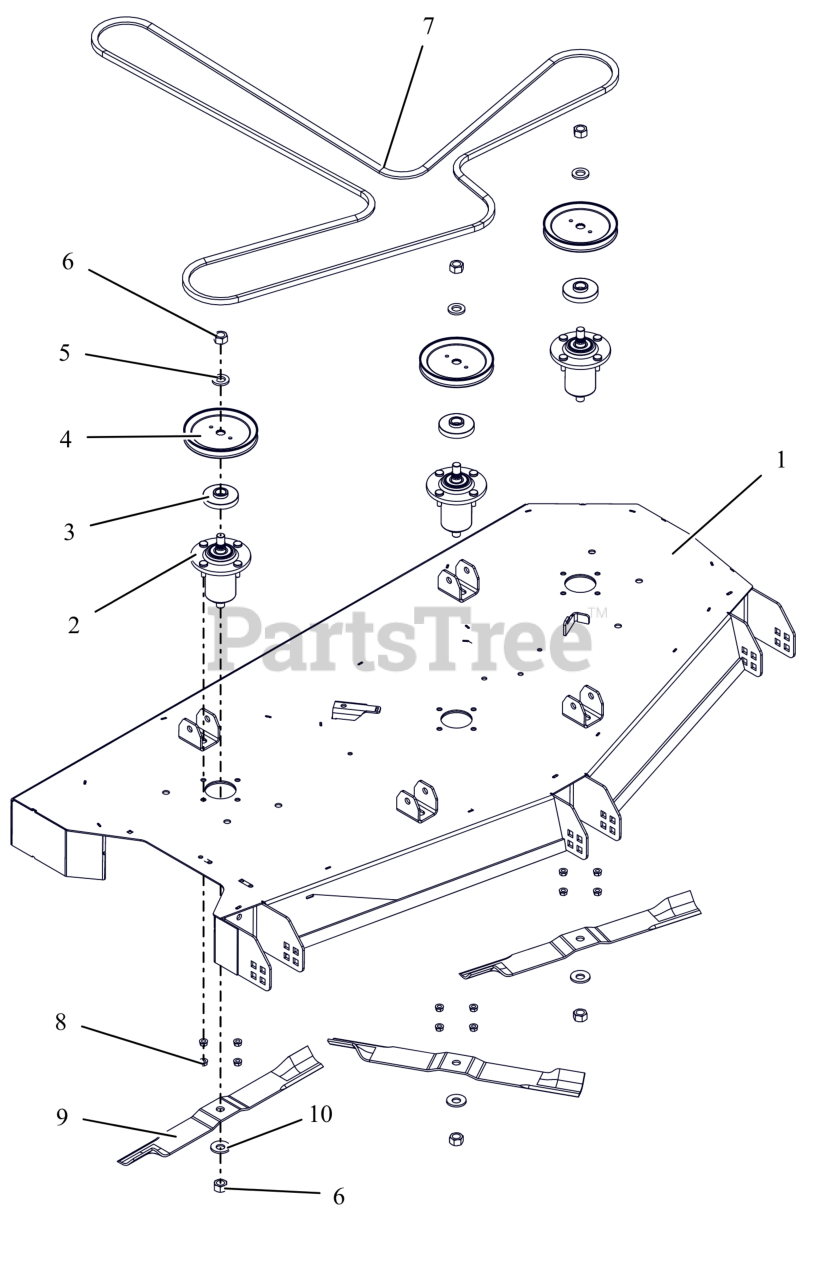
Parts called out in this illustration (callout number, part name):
1	KIT-GRAVELY DECK 60" W/ DECALS
2	ASM, ALUMINUM SPINDLE SUB
3	SHIELD, DUST
4	PULLEY-V-5.75 ODX.625SPLINE ID
5	SPCR- .735 X 1.313 X .165
6	NUT-STD .625-18 ZCC
8	NUT,LK-CTR-FLG .31-18 GF ZCC
9	BLADE- 20.5" MOWER (HI-LIFT)
10	WSHR-BLVL .669X1.535X.138
